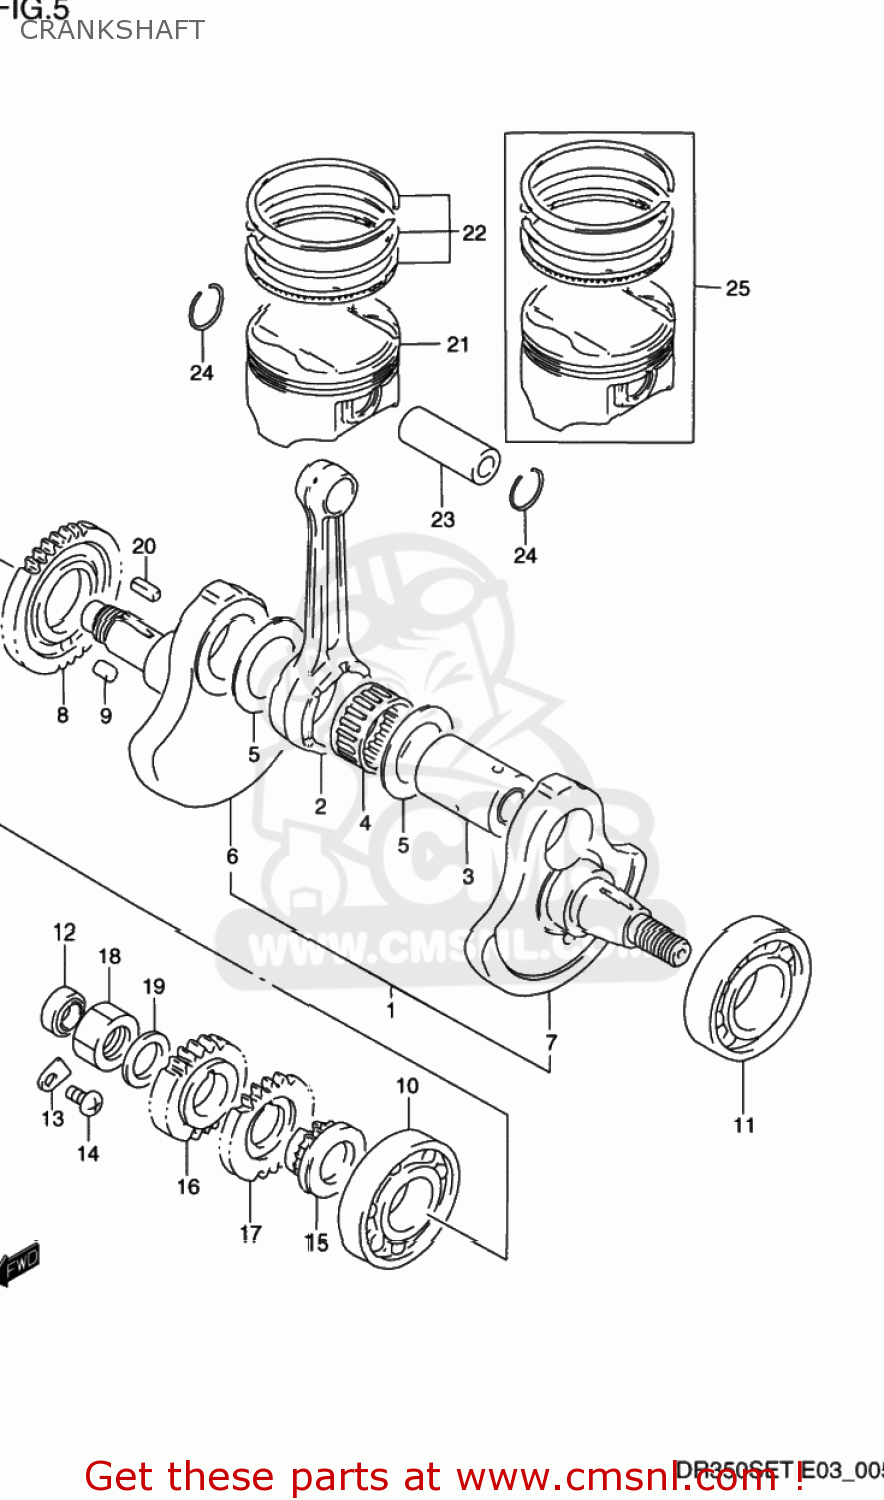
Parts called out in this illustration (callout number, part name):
1	CRANKSHAFT ASSY
2	ROD,CONNECTING
3	PIN COMP,CRANK
4	BEARING(34X43X22)
5	WASHER(34X52X1)
6	CRANKSHAFT
7	CRANKSHAFT,L
8	GEAR,CRANK BAL DRIVE(NT:37)
9	PIN
10	BEARING(30X72X19)
11	BEARING(35X72X17)
12	SEAL,OIL(14X24X6)
13	RETAINER,BEARING
14	SCREW
15	SPROCKET,CAM CHAIN DRIVE
16	GEAR,PRIMARY DRIVE
17	GEAR,OIL PUMP DRIVE (NT
18	NUT
19	WASHER
20	KEY
21	PISTON
22	RING SET,PISTON
23	PIN,PISTON
24	CIRCLIP,PISTON PIN
25	PISTON SET (OS:1.0)
